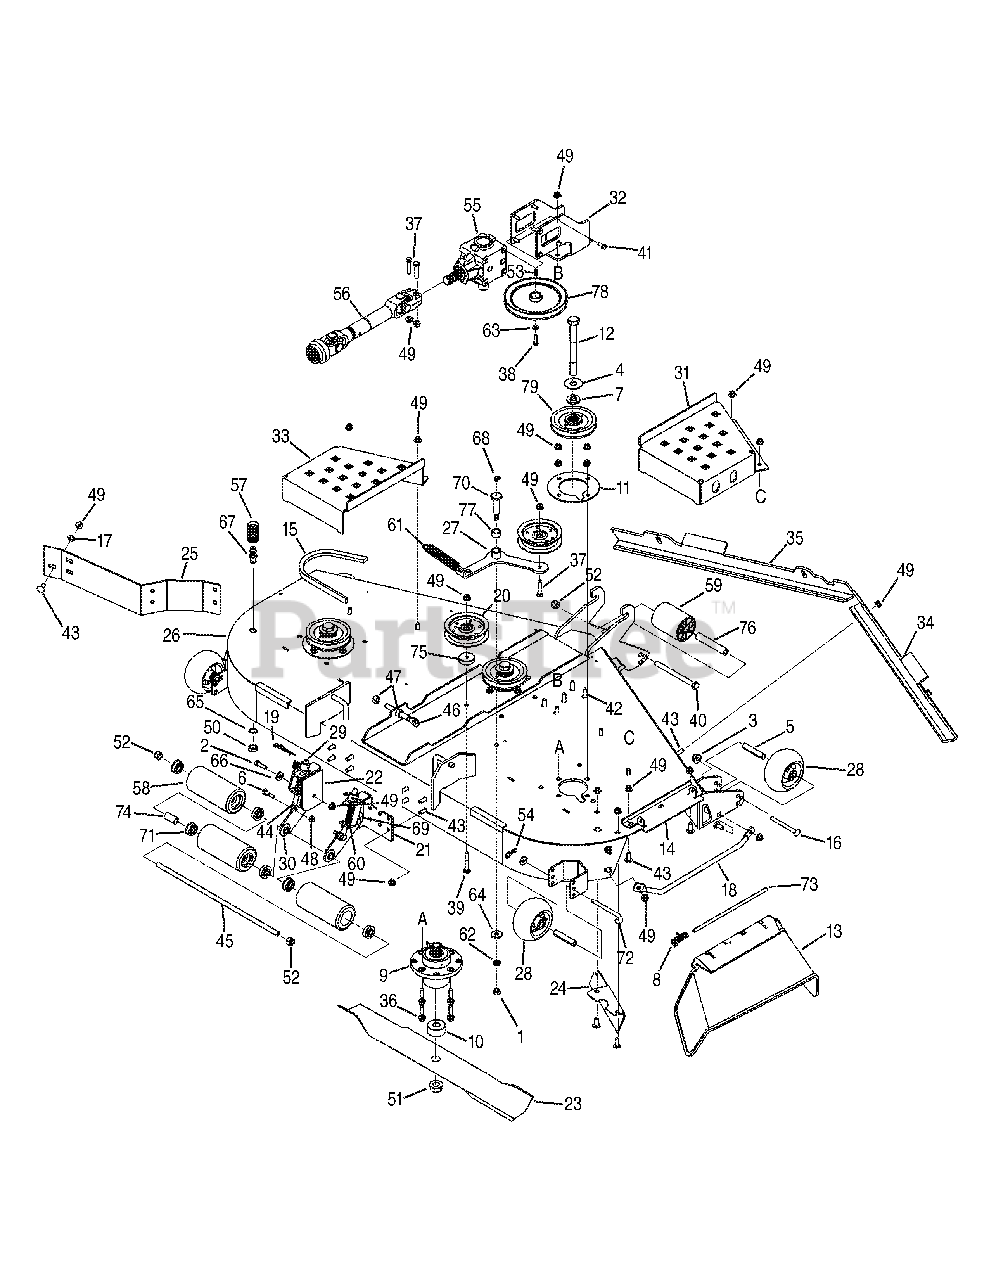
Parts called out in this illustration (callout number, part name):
1	Nut, 7/16-14
2	Hex Screw, 3/8-16 x 1-1/4
3	Flange Lock Nut, 3/8-16
4	Washer, .781 x 2.00 x .105
5	Spacer, .390 x .620 x 3.04
6	Shoulder Bolt, .372 x .484 x 5
7	Spacer, .812 x 1.47 x .218
8	Torsion Spring, .639 x 2.16 x .1
9	Spindle Assembly
10	Spacer, .760 x 2.00 x .925
11	Support Plate
12	Hex Screw, 3/4-16 x 7.00
13	Chute Deflector
14	Chute Bracket
15	Deck Belt
16	Carriage Bolt, 3/8-16 x 4
17	Push Nut, .335 x .780 x .01
18	Finger Guard
19	Hitch Pin, .120 x 3.00
20	Idler Pulley, 4.88
21	RH Striper Mount Bracket
22	LH Striper Mount Bracket
23	Blade, 21.0
24	Chute Baffle, 10.0
25	Adjustable Baffle, 60
27	Idler Arm Assembly
28	Wheel, 5.00
29	Striper Adjustment Assembly
30	Striper Bracket Assembly
31	RH Belt Cover
32	Mount Bracket
33	LH Belt Cover
36	Hex Flange Bolt, 3/8-16 x 1.5
37	Hex Screw, 3/8-16 x 1.75
38	Hex Screw, 5/16-18 x 1.00
39	Carriage Bolt, 3/8-16 x 2.50
40	Hex Screw, 1/2-13 x 6.0
41	Hex Screw, 5/16-18 x .75
42	Carriage Bolt, 3/8-16 x 1.25
43	Carriage Bolt, 3/8-16 x 1.0
44	Striper Height Rod
45	Striper Roller Shaft
46	Adjustable Eyebolt Link
47	Hex Nut, 1/2-13
48	Flange Lock Nut, 5/16-18
49	Flange Lock Nut, 3/8-16
50	Hex Nut, M16-1.5
51	Flange Lock Nut, 3/4-16
52	Hex Lock Nut, 1/2-13
53	Square Key, 1/4 x .75
54	Internal Cotter Pin
56	Drive Shaft
57	Water Nozzle Adapter
58	Roller, 6.5
59	Deck Roller
60	Compression Spring
61	Extension Spring
62	Lock Washer, 7/16
63	Flat Washer, .344 x .688 x .065
64	Flat Washer, .450 x 1.250 x .164
65	Lock Washer, 17 x 23.8 x 1.95
66	Flat Washer, .406 x 1.00 x .105
67	Deck Water Nozzle
68	Grease Fitting, 3/16
69	Shoulder Spacer, .6250 x .190
70	Shoulder Spacer, 7/16-14 x .68 x 2.11
71	Roller Bearing, .5
72	Roller Pin Rod
73	Chute Deflector Rod
74	Spacer, .75 x .53 x 1.5
75	Idler Spacer
76	Spacer, .510 x .75 x 4.375
77	Idler Spacer
78	Drive Pulley
79	Spindle Pulley, 4.6
